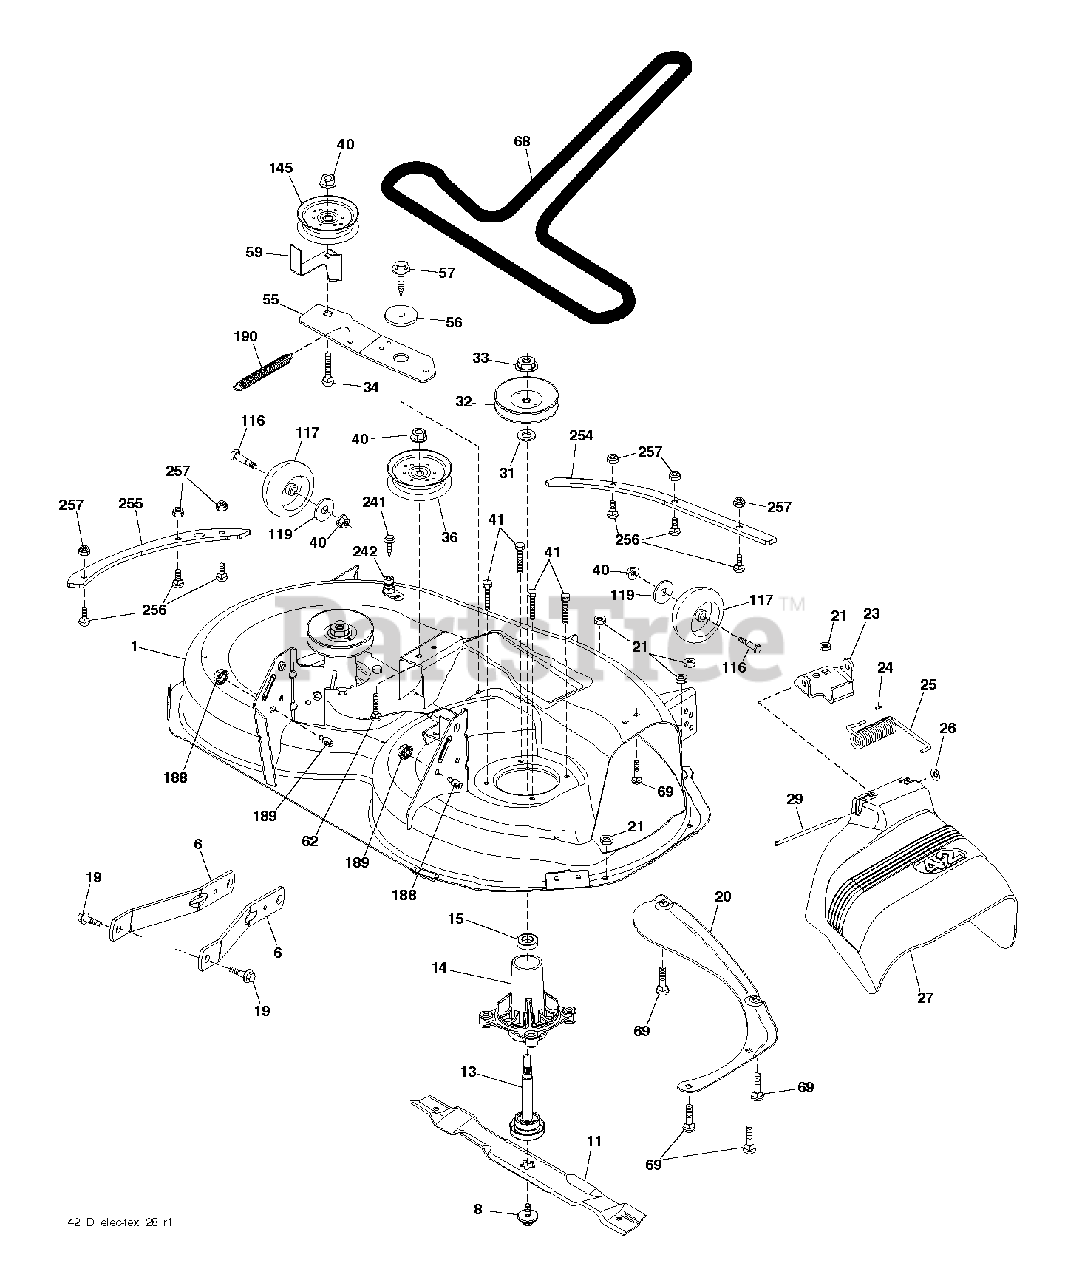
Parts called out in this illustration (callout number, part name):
1	DECK SVC 42B"445267X668
6	ARM.SUSPENSION.MOWER.R
8	BOLT.WASHER.ASM.7/16-2
11	42" HI-LIFT BLADE
13	SHAFT.ASM.MDRL.N/GREASE.38
14	HOUSING.MANDREL.4PT.
19	BOLT.SHOULDER
20	BAFFLE.VORTEX
21	LOCKNUT
23	BRKT.DEFLECTOR.38"2005+
24	CAP-SLEEVE LT
25	SPRING.TORSION.DEFLECT
26	NUT PUSH M
27	SHIELD.DEFLECTOR.MOWER.42"BLAC
29	ROD.HINGE
31	WASHER.SPACER.MANDREL
32	PULLEY/MANDREL
33	NUT.FLANGE.LOCK.TOP
34	BOLT.3/8-16X1.50
36	PULLEY.IDLER.2006
40	NUT LOCK FLG 3/8-16 UNC
41	BOLT.HEX.WASHR.HED.313-18X1.19
55	IDLER.ARM.42"
56	SPACER.RETAINER
57	SCREW 3/8-16X1
59	GUARD, BELT
68	BELT V SECONDARY
69	BOLT
116	BOLT.SHOULDER.3/8-16X3-5/8.
117	WHEEL. GUAGE RALLY
119	WASHER
145	PULLEY.IDLER.48"PRIMARY
188	STUD.FASTNER.W/ANTI-ROTATE
189	NUT LOCK HEX FLANGE 5/16-18
190	SPRING.MOWER.DRIVE.ELECTRIC
241	SCREW.TT.#10-32X.5.3/8.FLANGE
242	PORT.WASHOUT
254	PLATES.RENFRC.42DECK.PT431FRNT
255	PLATES.RENFRCE.42DECK.X431SIDE
256	RHSNB, 1/4-20 X 1, GR5
257	NUT T
